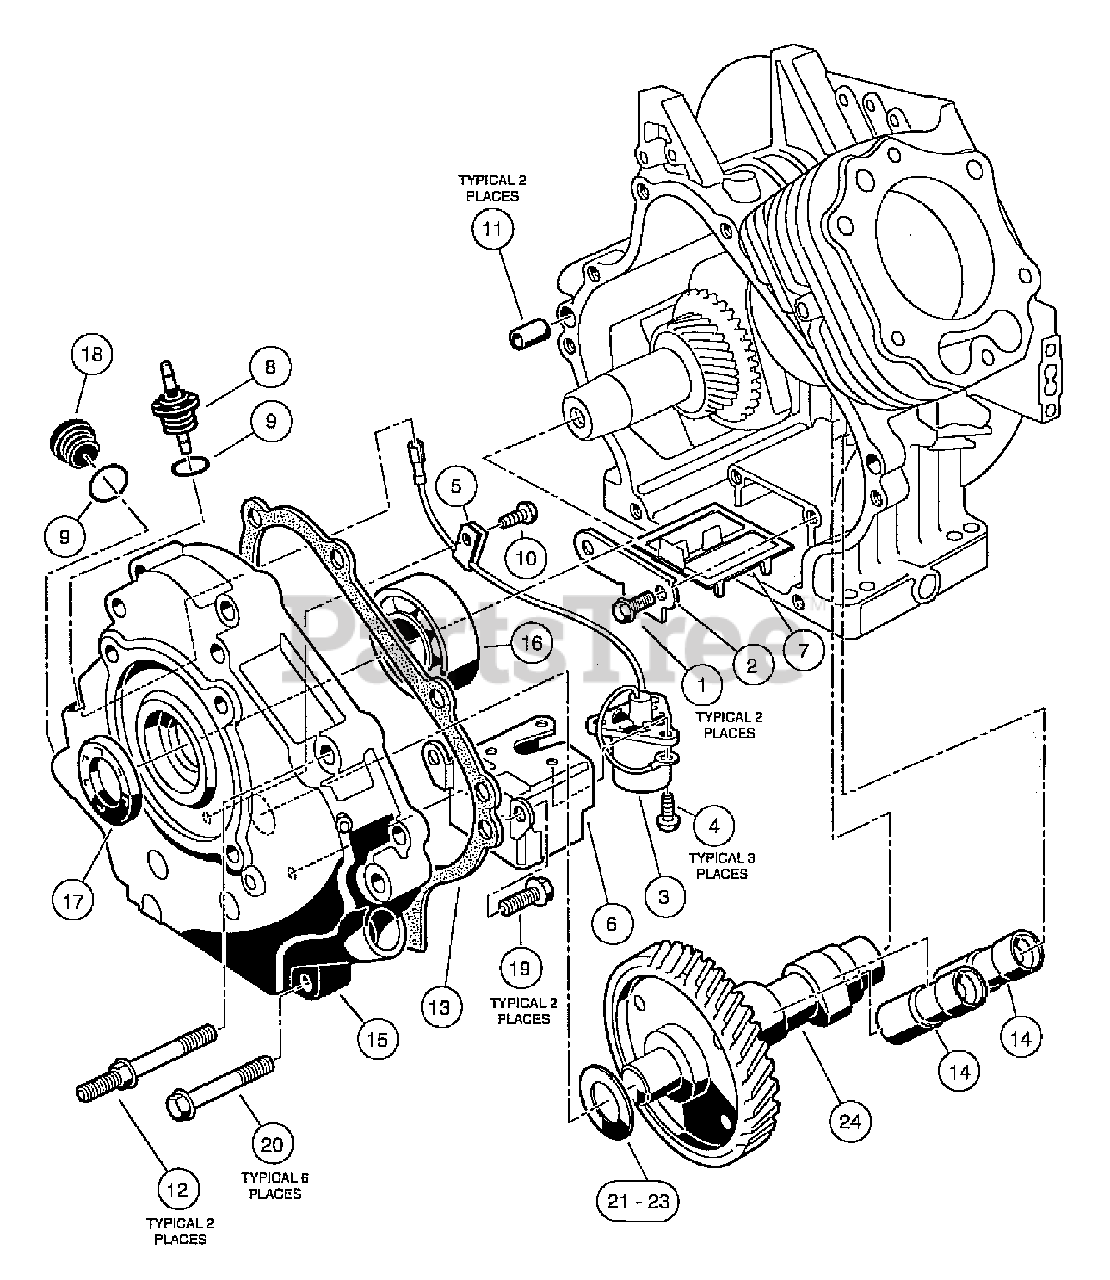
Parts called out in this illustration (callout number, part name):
1	Bolt, Flange Head, M5 x 0.8 x 6 mm
2	Plate, Oil Filter Screen
3	Sensor, Oil Level
4	Screw, Cross Pan-Head, M4 x 0.7 x 8 mm
6	Bracket, Switch, Oil Level
7	Screen, Oil Filter:
8	Connector, Cord
12	Bolt, Two-Ended, M8 x 1.25 x 69 mm
13	Gasket, Crankcase Cover
14	Adjuster, Lash
15	Cover Crankcase
16	Bearing, Ball
17	Seal, Oil
19	Bolt
20	Screw, M8-1.25 X 45mm Hex
24	Camshaft, FE350 without ACR, 44-Tooth
